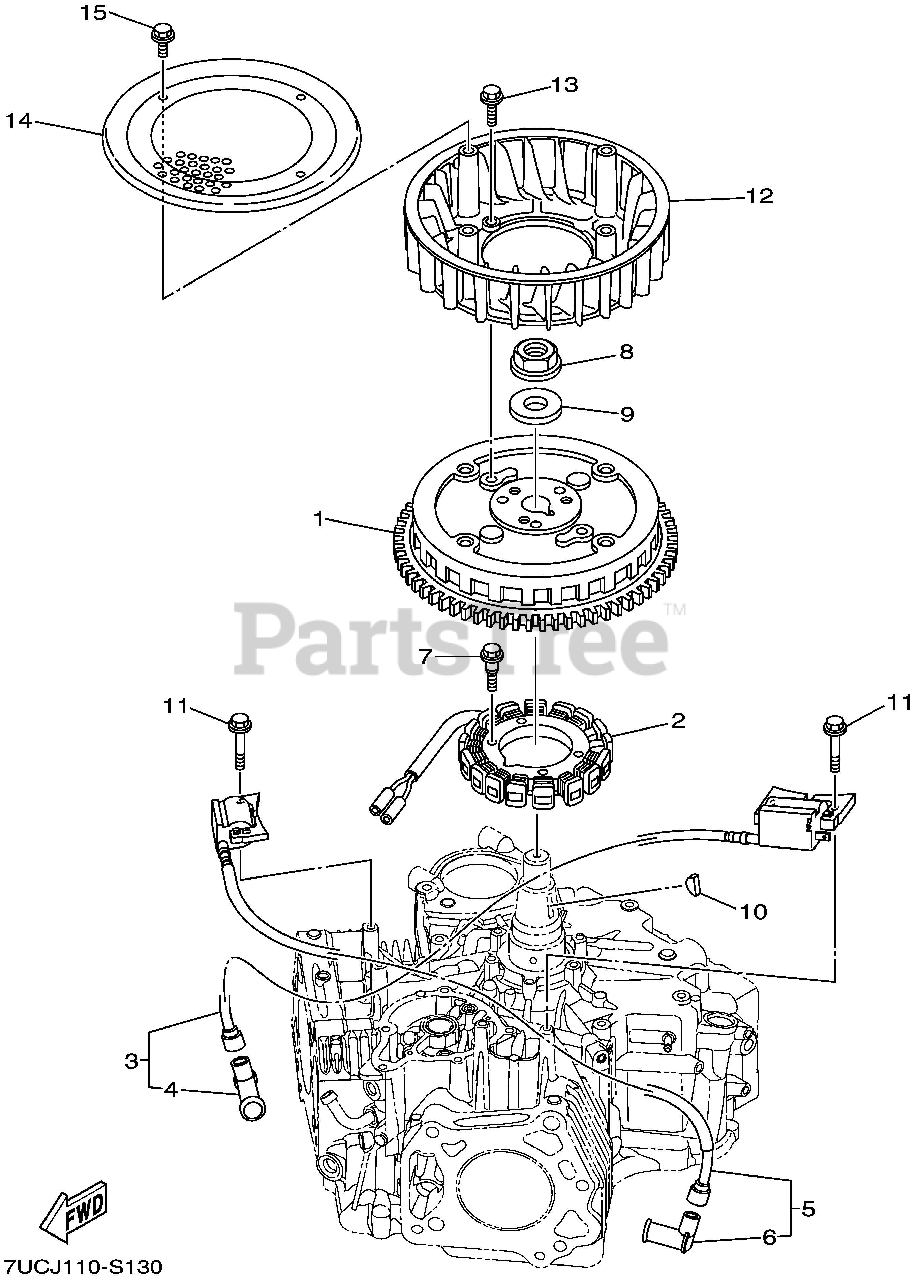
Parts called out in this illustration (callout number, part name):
1	ROTOR ASSY
2	STATOR ASSY
3	T.C.I. UNIT ASSY
4	PLUG CAP ASSY
5	T.C.I. UNIT ASSY
6	PLUG CAP ASSY
9	WASHER, PLATE
10	KEY, WOODRUFF
13	BOLT, FLANGE
15	BOLT, FLANGE
